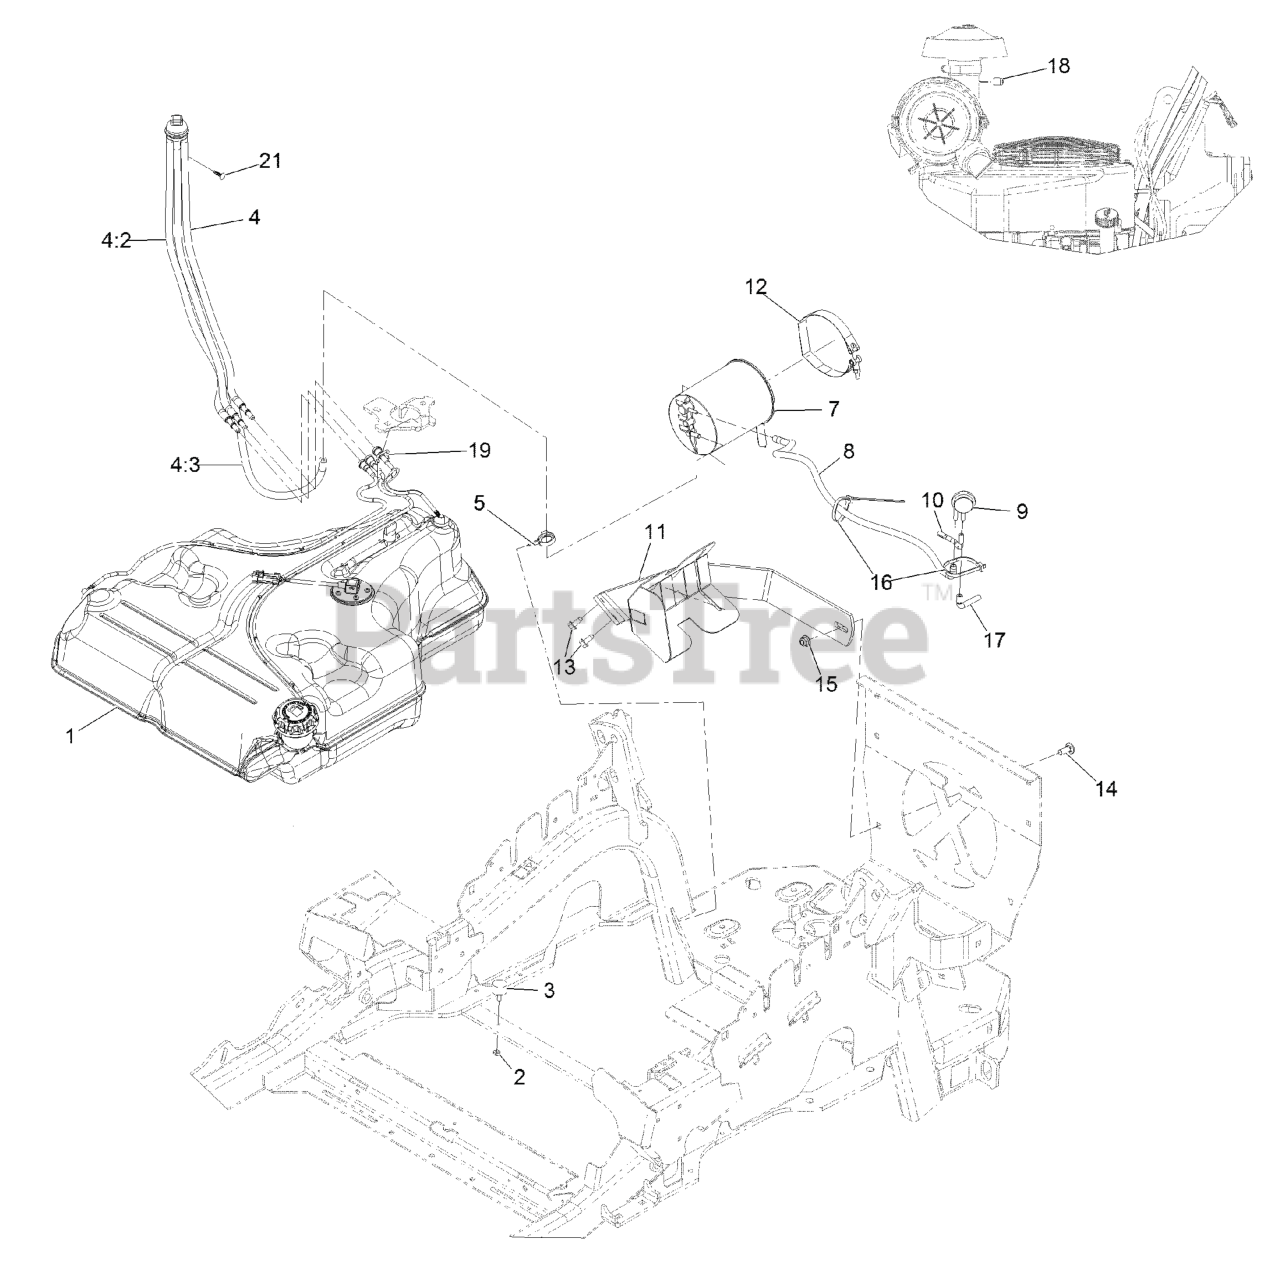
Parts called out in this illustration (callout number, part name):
1	FUEL TANK ASM
2	NUT-JAM
4	FUEL MANIFOLD VENT ASM
4:2	HOSE-FUEL
4:3	HOSE-FUEL
5	CLAMP-HOSE
7	CANISTER-CARBON, 1200CC
8	HOSE-VENT, FORMED
9	VALVE-CONTROL, VACUUM
10	HOSE-VENT, FORMED
11	MOUNT-CANISTER
12	CLAMP, T-BOLT
13	Screw-HWH 5/16-18 X 3/4 Tf
14	SCREW-CARR
15	NUT-HF, NI
16	TIE-PLASTIC
17	HOSE-VENT, FORMED
18	PLUG-PORT
19	RETAINER-LINE, VAPOR
21	PLUG-PLASTIC
